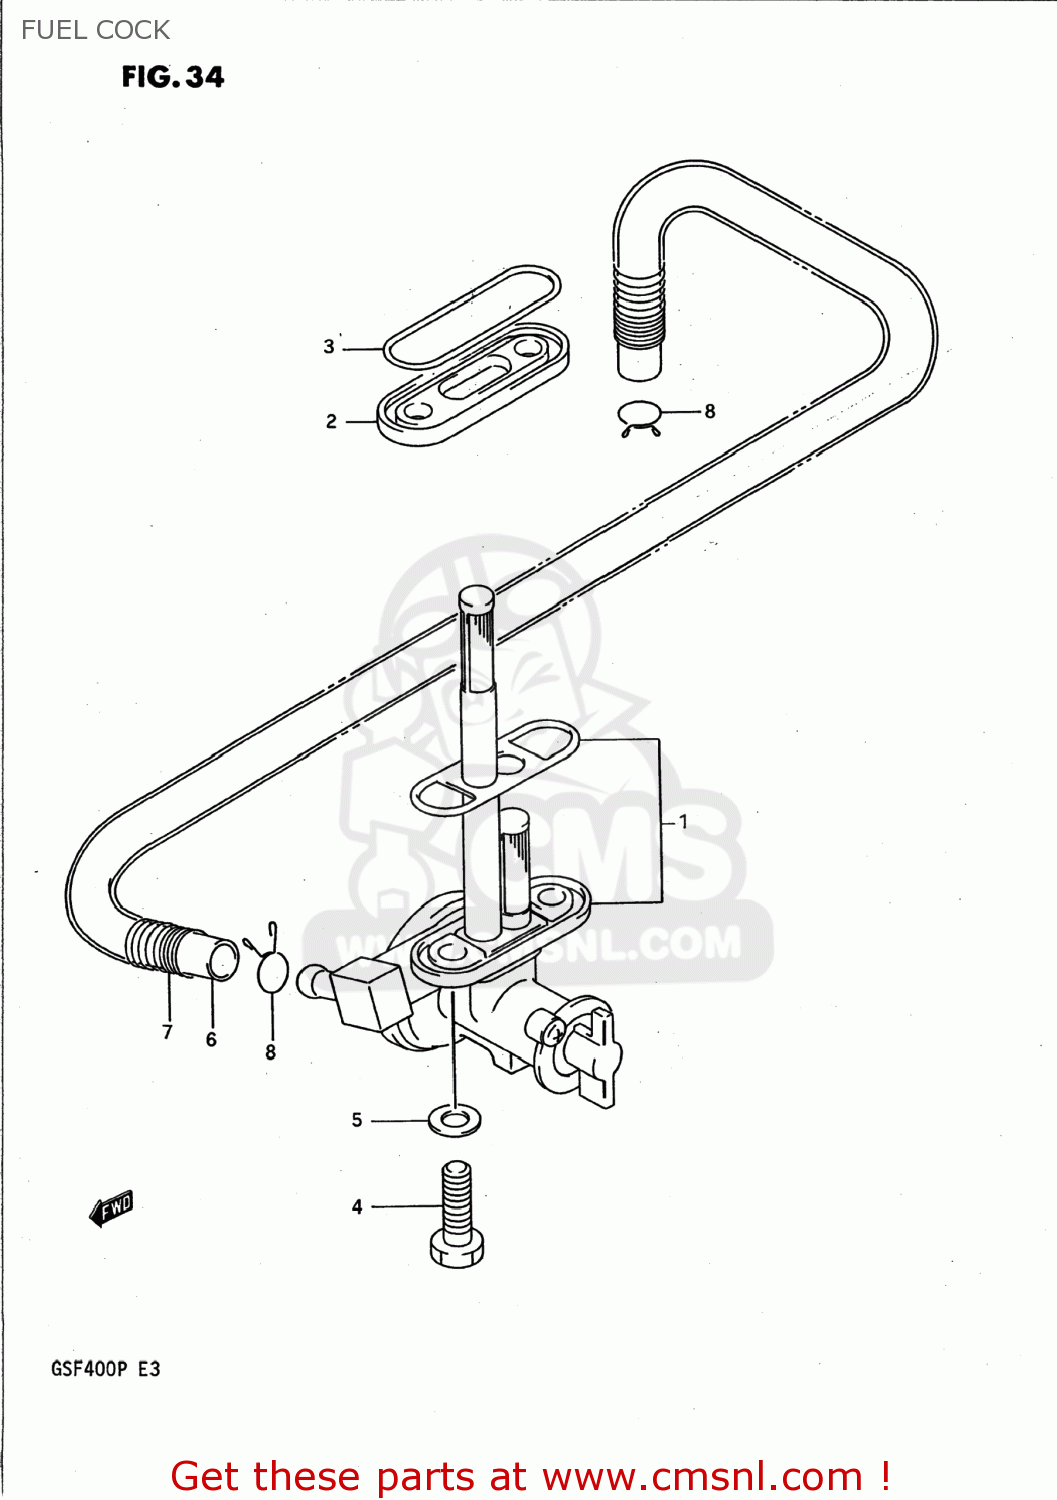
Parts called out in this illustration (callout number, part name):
1	COCK ASSY,FUEL
2	SPACER,FUEL COCK
3	GASKET,FUEL COCK (NAS)
4	SCREW (6X25)
5	GASKET(6.4X11.5X0.8) (NAS)
6	HOSE(7X10.2X600)
7	SPRING
8	CLIP
